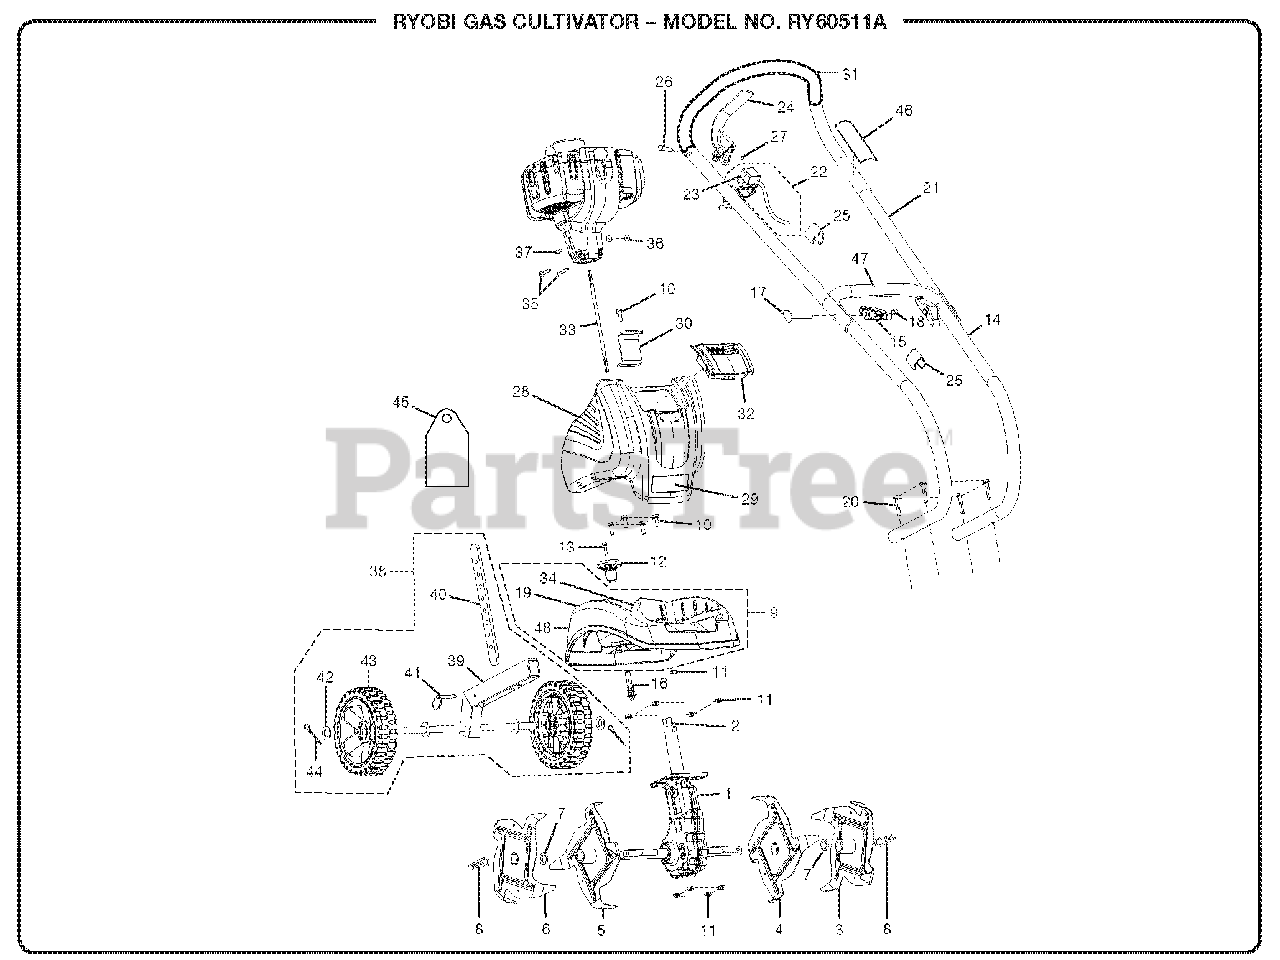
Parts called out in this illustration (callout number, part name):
1	GEAR BOX ASSEMBLY WITH TUBE
2	LINER - DRIVE TUBE
3	TINE A, OUTER RIGHT
4	TINE B, INNER RIGHT
5	TINE C, INNER LEFT
6	TINE D, OUTER LEFT
7	FELT WASHER
8	CLEVIS CLIP
9	TINE SHIELD ASSEMBLY ( INC. KEY NOS. 19, 34 AND 48)
10	BOLT (1/4-20 x 3/4 in.)
11	LOCK NUT (1/4-20)
12	RECEIVER RETAINER KNOB
13	SCREW (M5 x 15 mm PAN HD.)
14	LOWER HANDLE ASSEMBLY (INC. KEY NO. 47)
15	KNOB (1/4-20)
16	RECEIVER RETAINER ASSEMBLY
17	CARRIAGE BOLT (1/4-20 x 2-1/4 in.)
18	ACORN NUT
19	WARNING LABEL, FOOT
20	HANDLE BOLT (1/4-20 x 1.53 in.)
21	UPPER HANDLE ASSEMBLY (INC. KEY NO. 31 AND 46)
22	THROTTLE CABLE ASSEMBLY (INC. KEY NO. 23)
23	SWITCH
26	CLEVIS PIN
27	RETAINING RING
28	TANK - BALLAST ASSEMBLY (INCLUDES KEY NO. 29)
29	LOGO LABEL
30	MOUNTING BRACKET
32	BALLAST TANK LID
33	FLEXIBLE DRIVE SHAFT
34	WHEEL ACCESSORY LABEL
35	BOLT (10-24 x 1-1/4 in.)
36	LOCK NUT (10-24)
37	SCREW (8-16 x 1/2 in.)
38	WHEEL/DRAG STAKE ASSEMBLY (INCLUDES KEY NO. 39-44)
39	FRAME ASSEMBLY
40	DRAG STAKE
41	QUICK RELEASE PIN
42	FLAT WASHER
43	WHEEL ASSEMBLY (7 in. DIA.)
44	COTTER PIN
45	WARNING HANG TAG
46	BOOM WARNING LABEL
47	STARTING LABEL
48	WARNING LABEL
